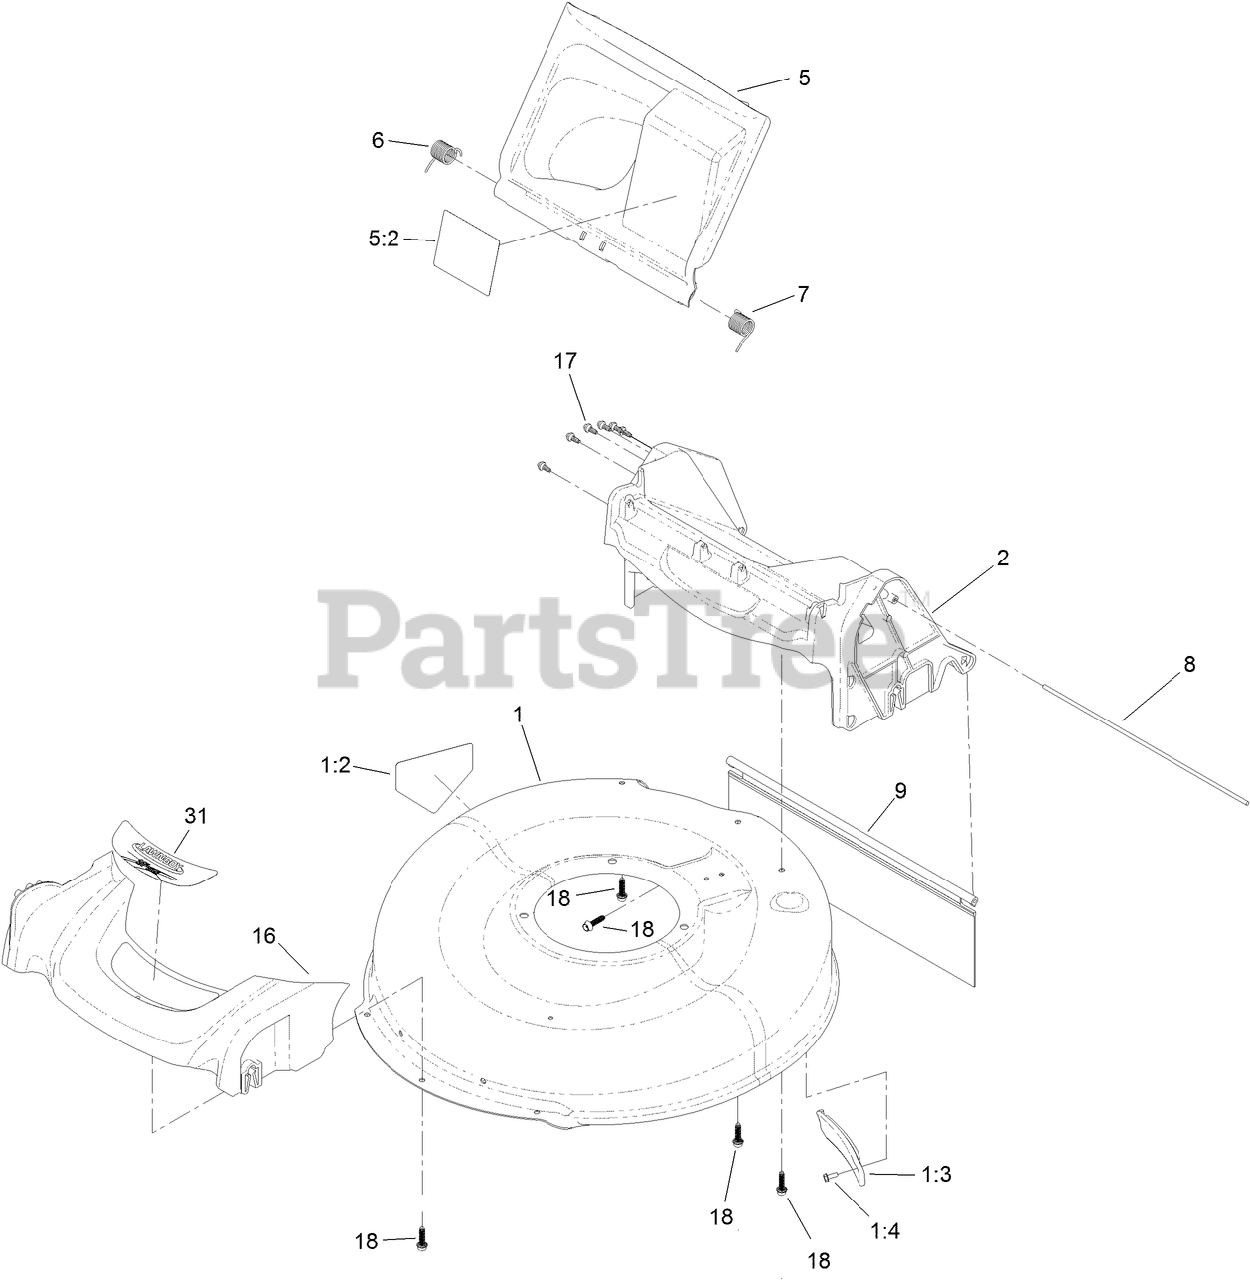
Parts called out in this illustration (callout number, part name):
1	HOUSING ASM
1:2	DECAL-DANGER
1:3	COVER-BELT
1:4	SCREW-TAPTITE
2	CHUTE ASM
5	REAR DEFLECTOR ASM
5:2	DECAL-WARNING
6	SPRING-TORSION
7	SPRING-TORSION
9	SHIELD-TRAILING
18	SCREW-FLANGE, PLASTIC
31	DECAL-DECK
